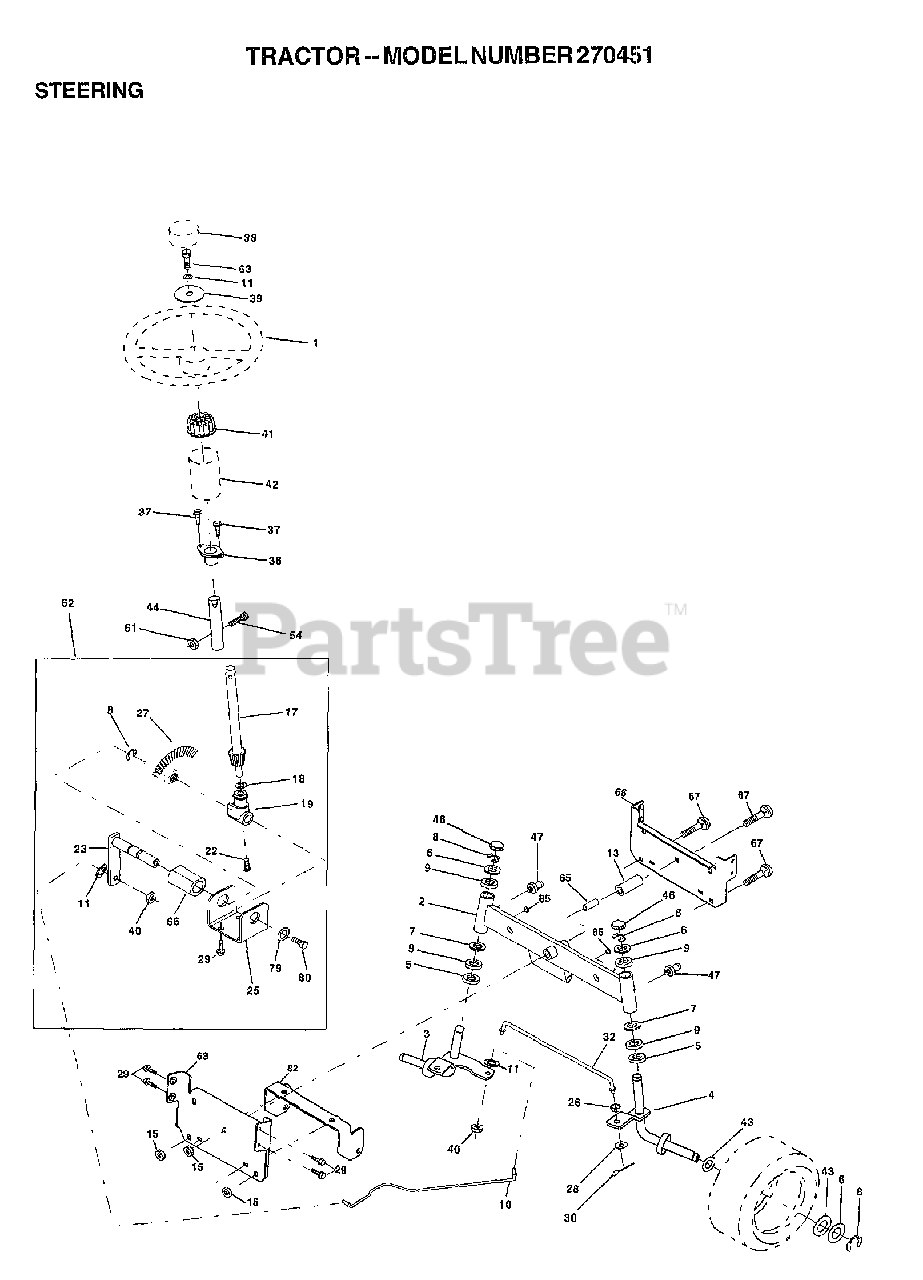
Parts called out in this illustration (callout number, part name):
1	WHEEL STR AYP BLK
2	AXLE ASM
3	SPINDLE.ASM.LH
4	"SPINDLE ASM,RH"
5	WASHER .T
6	WASHER
7	WASHER
8	RING
9	COL. SRTG. BEAR.
10	LINK DRAG
11	LOCKWASHER
13	SPACER BEARING
15	NUT.HXFLG.LOCK.
17	SHAFT ASM STEERIN
18	THRUST WASHER
19	SUPPORT.SHAFT.STEER
22	SCREW.HX.WSH.HD
23	SHAFT.ASM.PITMAN
25	BRKT-STEERING
26	BUSHING.DRAGLINK
27	GEAR SECTOR
28	WASHER
29	SCREW
30	COTTER PIN
32	TIE ROD
36	BUSHING.STEERING
37	"SCREW-TT,10-32 FL"
38	CAP STEER AYP
39	WASHER
40	GRIPCO NUT
41	ADAPTER LT
42	BOOT.STEERING.DASH.P/L
43	WASHER
44	EXT SHAFT STEERIN
46	CAP
47	ZERK M
51	NUT
54	BOLT
62	KIT.STEER.ASM
63	BOLT
65	"SPACER BRCAE,AXLE"
66	"BEARING-ARM,PITMA"
67	BOLT RDHD 3/8-16
68	BRACE AXLE
79	WASHER
80	BOLT.HX.NYLON3/8-16X3/
82	BRKT SUSP CHASSIS FRT
85	XMAS TREE FASTNER
